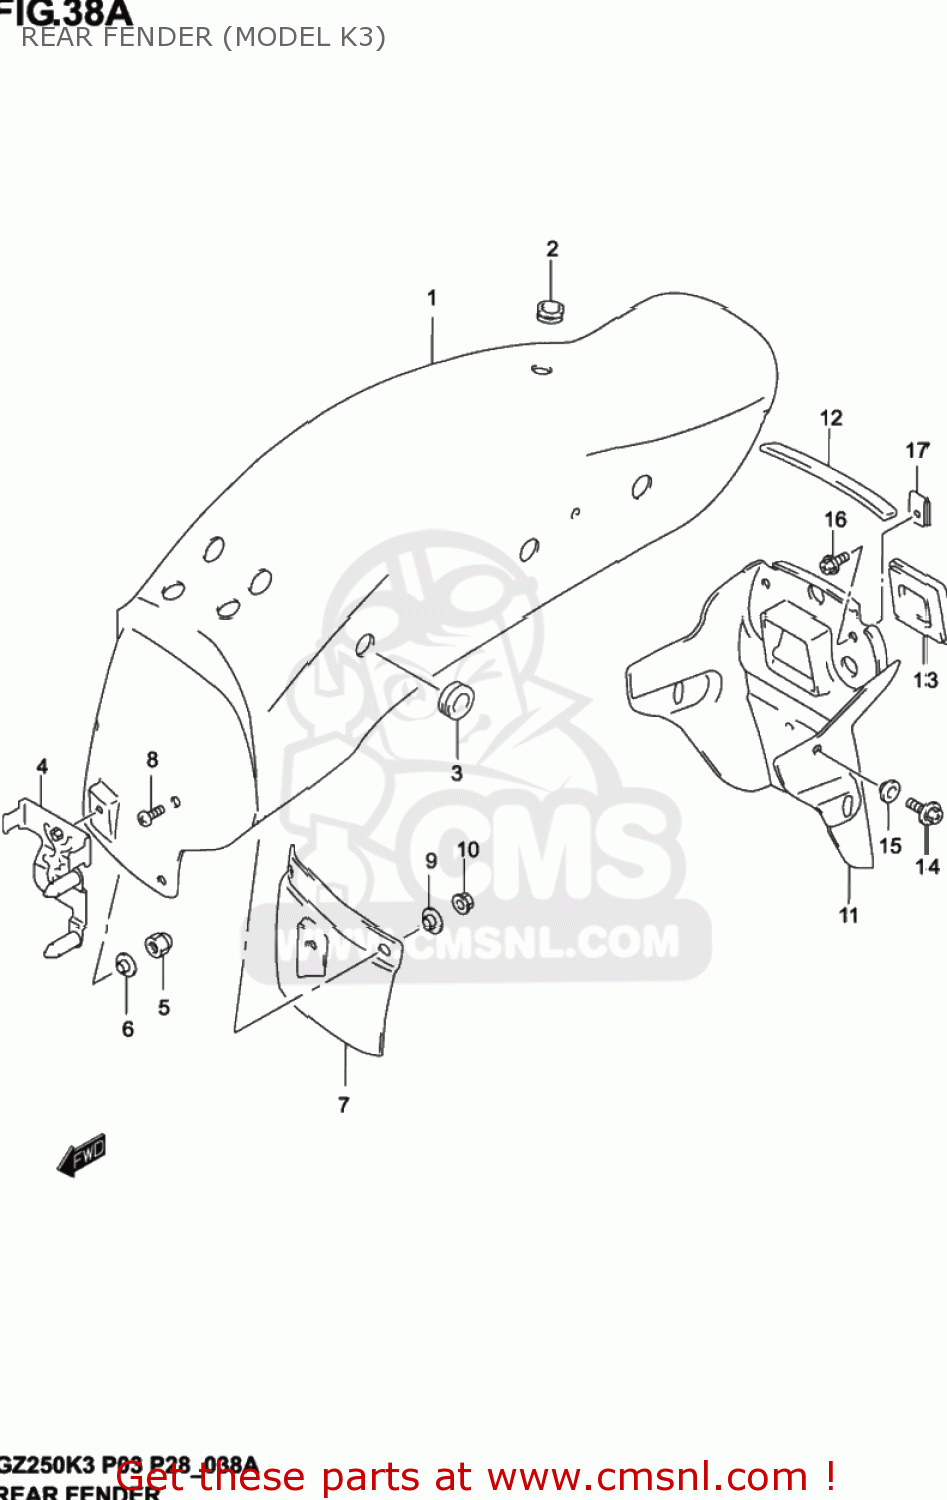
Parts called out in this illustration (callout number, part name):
1	FENDER,RR
2	CUSHION
3	CUSHION,RR FENDER
4	BRACKET,RR FENDER
5	NUT
6	WASHER
7	MUDGUARD,RR FENDER
8	SCREW
9	WASHER
10	NUT
11	EXTENSION,RR FENDER
12	CUSHION,RR FENDER EXTENSION
13	CAP,RR FENDER EXTENSION
14	BOLT
15	WASHER
16	SCREW
17	PLATE,FRAME COVER
